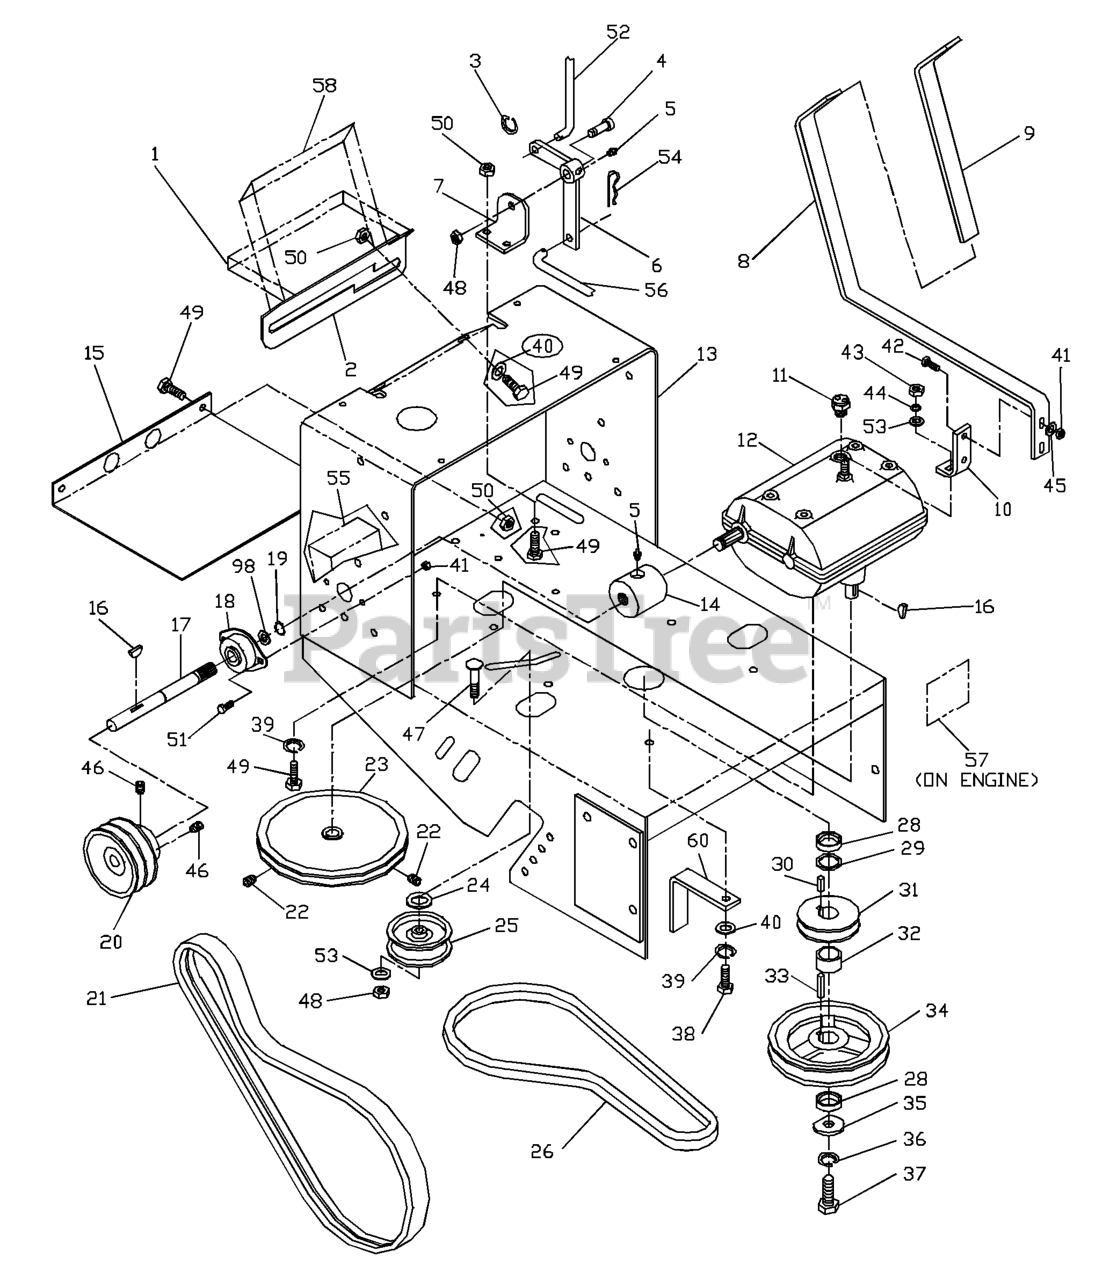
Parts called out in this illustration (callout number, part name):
1	DECAL, SHIFTER
2	SHIFTER PLATE
4	SB 12C X 34
5	ZERK
7	BRACKET-BELLCRANK-BLACK
8	SHIFTER ARM
9	SHIFTER GRIP
10	SHIFTER BRACKET
11	SWITCH, TRANS
12	TRANSMISSION WB
13	REAR DECK W/DECALS
15	LOWER BELT SHIELD
16	KEY, #9 WOODRUFF
17	DRIVE SHAFT
19	RETAINER RING
20	PULLEY, DRIVE (36 & 48)
20	DRIVE PULLEY (32)
21	BELT, DRIVE (36 & 48)
21	DRIVE BELT (32)
22	SETSCREW, 1/4-20 NYLOC
23	PULLEY, INPUT
24	WASHER 1/2 FLAT
25	IDLER PULLEY
26	BELT, TRANSMISSION
27	BELT GUIDE
29	BUSHING, 10GA MACHINERY
30	KEY 1/4 SQ X 3/4
33	KEY 1/4 SQ X 1 1/8
34	PULLEY, ENGINE
35	WASHER, CRANKSHAFT
36	WASHER 7/16 LOCK
37	HCS M10-1.5X35MM
37	HCS 7/16F X 1 1/2
38	HTB M8-1.125 X 25MM
38	HCS M8-1.25 X 30MM
39	WASHER.LOCK.HVY.HLCL.SPR.5/16
40	WASHER 5/16 FLAT
41	NUT 1/4C CENTER LOCK
42	HCS 1/4C X 1
44	SLW 3/8 STD
45	WASHER 1/4 FLAT
46	SET SCREW 5/16 NYLOC
46	(32" MODELS)
47	RHSNB 3/8C X 2
48	NUT 3/8C CENTERBLOCK
49	HCS 5/16C X 3/4
50	NUT 5/16C CENTERLOCK
51	HCS 1/4C X 5/8
53	WASHER 3/8 FLAT
54	HAIRPIN #4
55	DECAL, DANGER
56	BLADE ROD 48"
56	BLADE ROD 36"
57	DECAL, EXHAUST
58	DECAL, CLUTCH
59	BUSHING
60	BELT GUIDE - LONG
60	48" MODELS
60	32" & 36" MODELS
